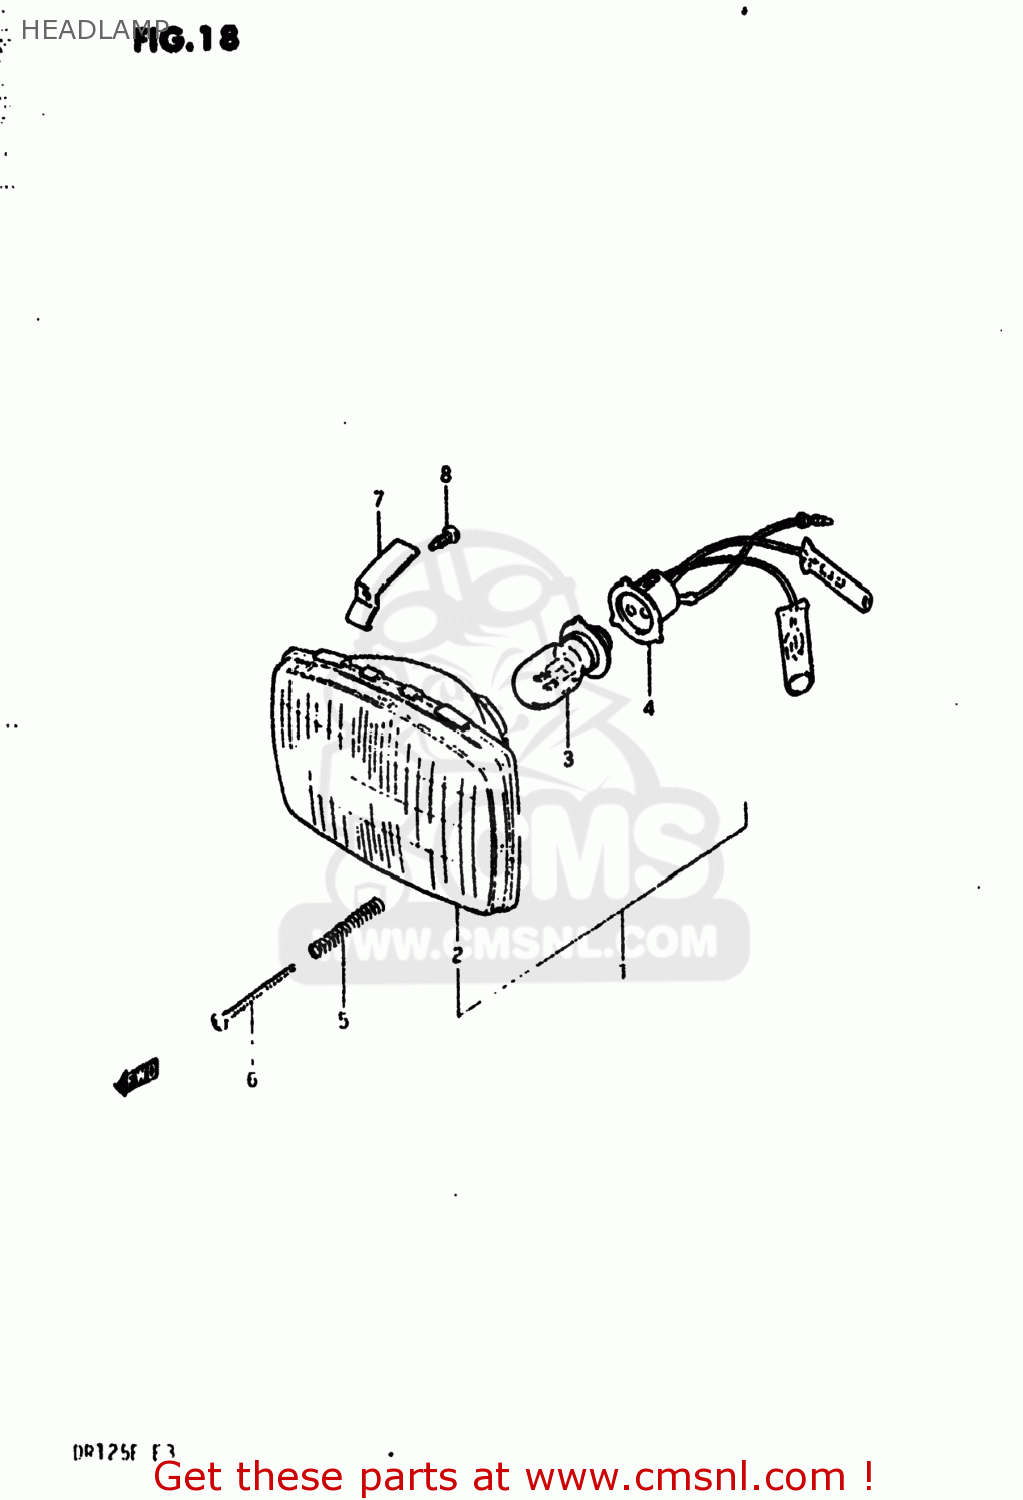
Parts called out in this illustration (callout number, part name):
1	HEADLAMP ASSEMBLY
2	LAMP UNIT
3	BULB(6V15/15W/STANLEY,A3598HA)
4	SOCKET,HEADLAMP
5	SPRING,HEAD LAMP ADJUSTER
6	SCREW,HEADLAMP ADJUST
7	SPRING
8	SPRING,HEADLAMP ADJUST
